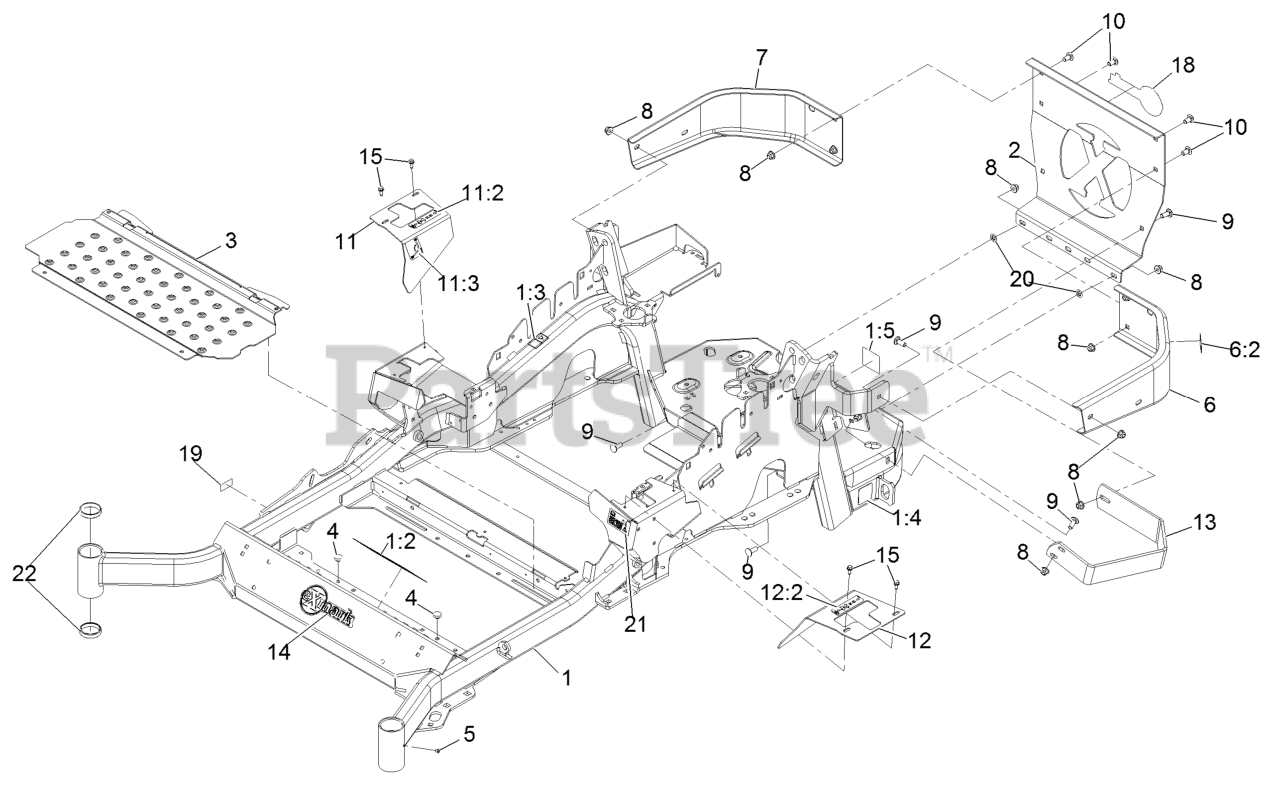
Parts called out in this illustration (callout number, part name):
1:2	DECAL-DANGER
1:3	DECAL-WARNING
1:4	DECAL-HAZARD, PINCHED FINGER
1:5	DECAL-SPARK ARRESTER
2	PLATE,REAR GUARD
6	LH BUMPER ASM
6:2	DECAL-WARNING
7	BUMPER-RH
8	NUT-HF, NI
9	SCREW-CARR
10	SCREW-CARR
11	RH MOTION CONTROL COVER ASM
11:2	DECAL-CONTROL, MOTION
11:3	DECAL-PARK BRAKE, CE
12	LH MOTION CONTROL COVER ASM
12:2	DECAL-CONTROL, MOTION
13	GUARD-MUFFLER
14	DECAL-EXMARK LOGO
15	SCREW-HWH
18	DECAL-EXMARK LOGO
19	Decal-Patent Ttco.Com
20	NUT-PUSH
21	DECAL-FUEL FILL, CE
22	CUP-BEARING
